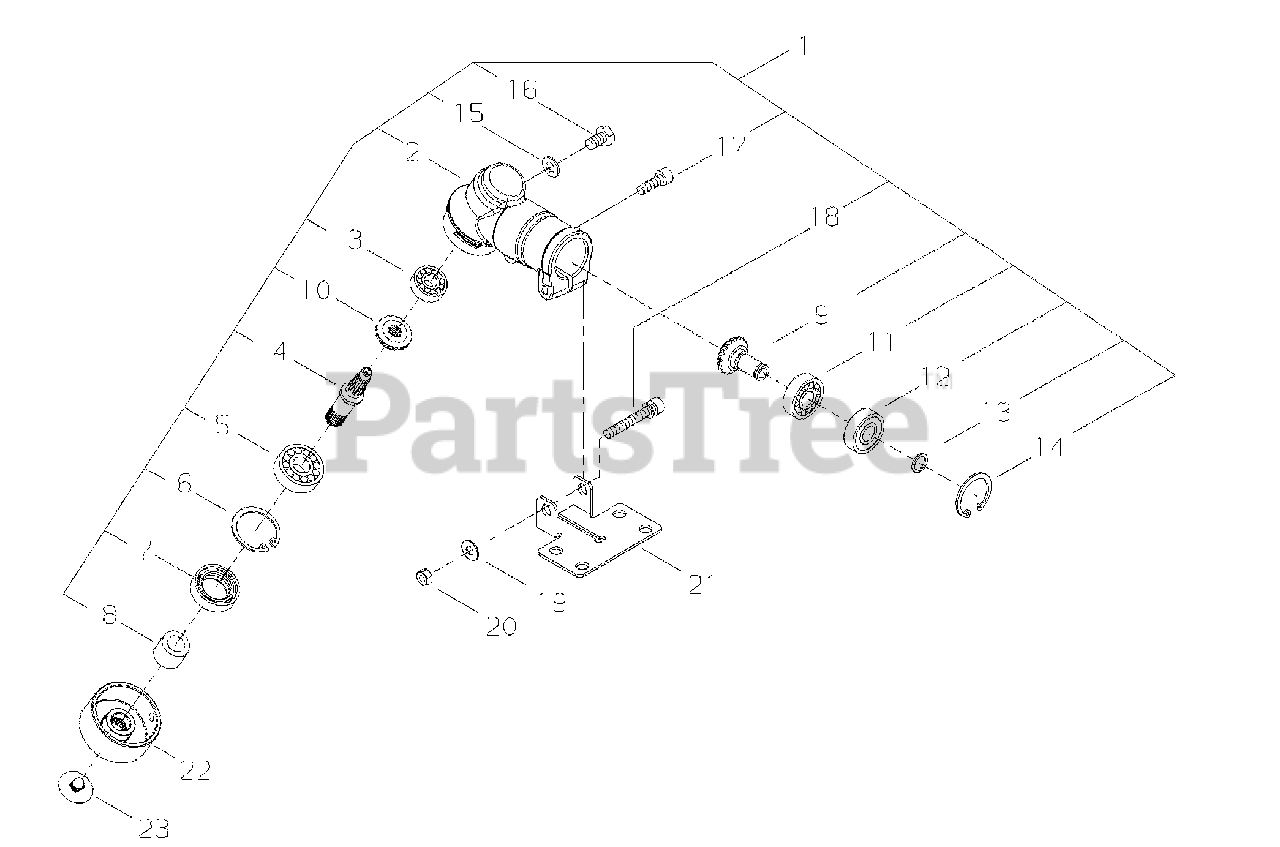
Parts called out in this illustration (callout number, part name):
1	GEAR CASE ASSY
2	CASE, GEAR
3	BEARING, BALL - 626MOS
4	GEAR - SHAFT
5	BEARING, BALL - 6000MOS
6	RING, RETAINING - 26
7	SEAL, OIL
8	COLLAR
9	GEAR - SHAFT
10	GEAR - BEVEL
11	BEARING, BALL - 609 MOS
12	BEARING, BALL - 609Z MOS
13	RING, RETAINING - 9
14	RING, RETAINING - 24
15	WASHER - 6
16	BOLT - 6X10
17	SCREW - 5X10
18	SCREW - 5X40
19	WASHER - 5
21	MOUNTING PLATE, SHIELD
22	HOLDER
